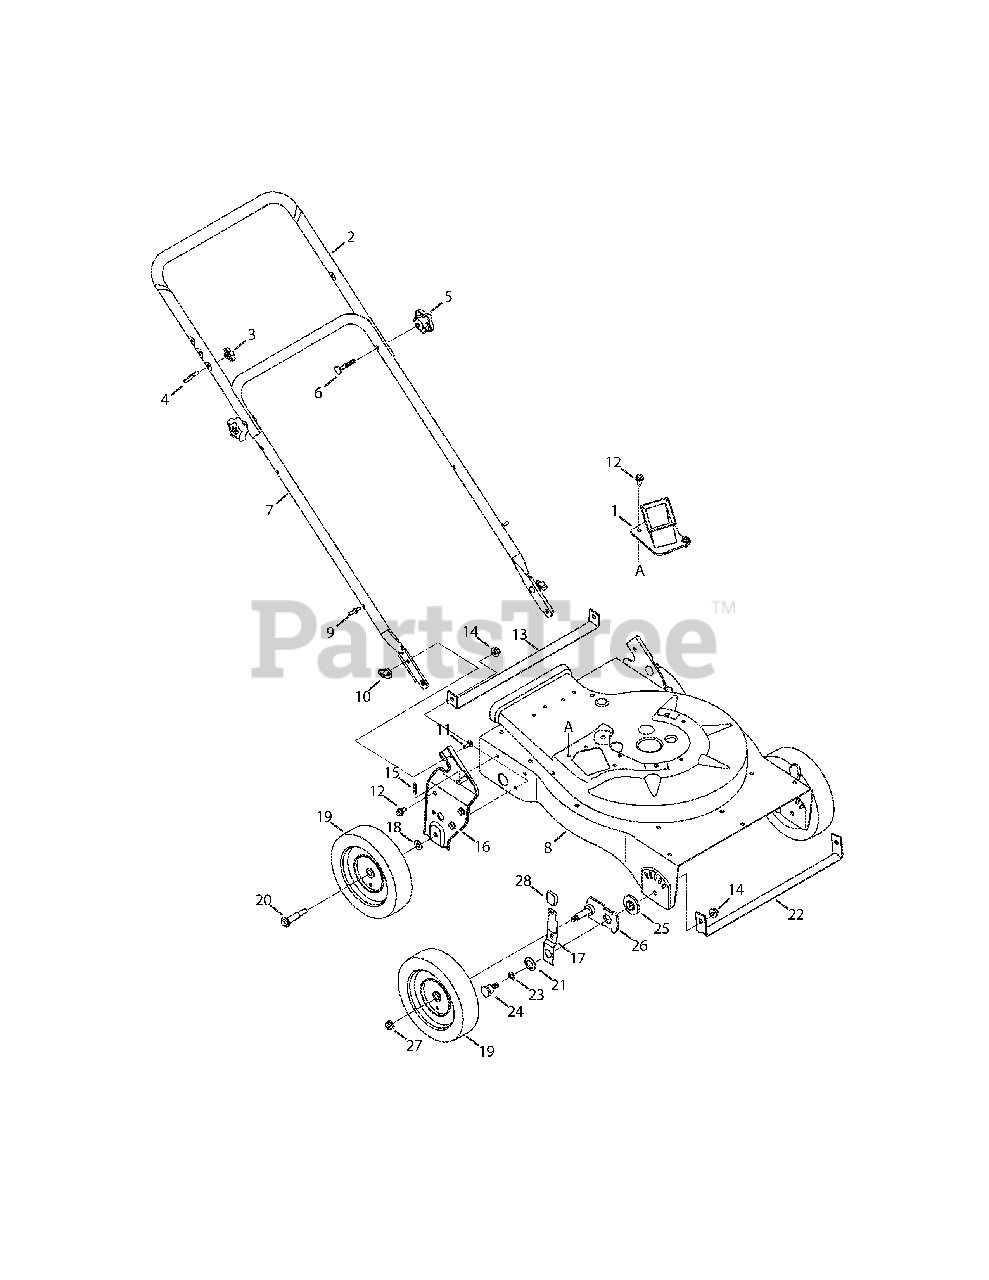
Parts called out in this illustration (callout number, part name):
2	Upper Handle
4	Eye Bolt
5	Star Knob, 5/16-18
6	Carriage Bolt
7	Lower Handle
10	Wing Nut 1/4-20
11	Carriage Screw 1/4-20 x.75
12	Screw, 5/16-12 x.750
13	Rear Wheel Support Brace
14	Flange Lock Nut, 3/8-16
15	Cotter Pin
16	Handle Bracket Assy. LH
17	Spring Lever
18	Bell Washer.401 ID x.870 OD
19	Wheel, 8 x 1.8, Bar
20	Shoulder Screw 3/8-16
21	Bell Washer.760 ID x.25OD
22	Front Wheel Support Brace
23	Thrust Washer.375 ID x.70 OD
24	Shoulder Screw, .750 ID x .500
25	Height Adjustment Bearing
26	Pivot Arm Assembly
27	Flange Lock Nut, 3/8-16
28	Height Adjustment Knob
